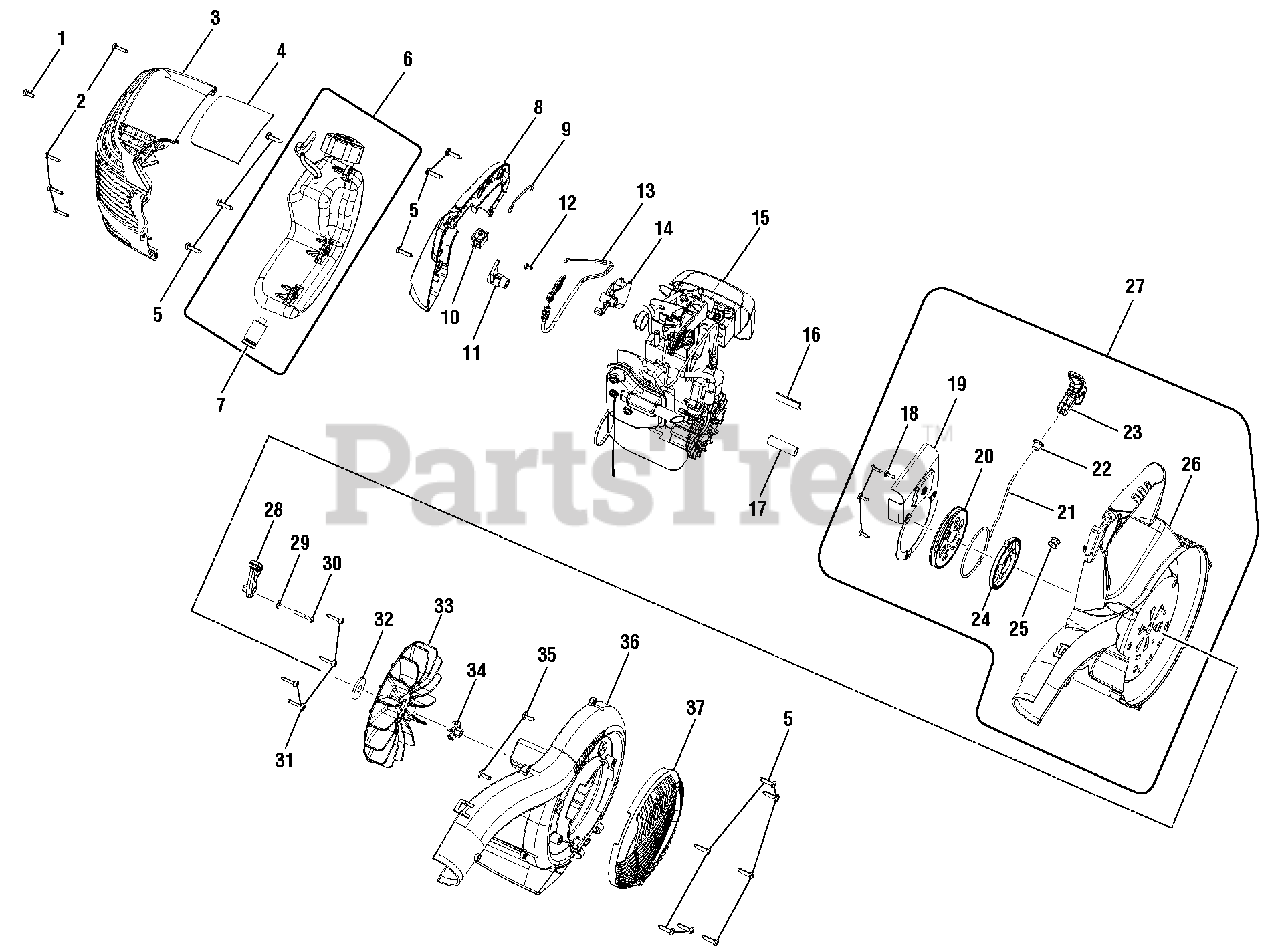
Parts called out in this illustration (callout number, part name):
1	Screw (M5 x 10.5 mm, T20 Torx Hd. )
2	Screw (M4 x 18 mm, T20 Torx Soc. Hd.)
3	Engine Housing
4	Heat Shield
5	Screw (#10-14 x 3/4 in, T25 Torx Pan Hd. T.F.)
6	Fuel Tank Assembly w/Cap
7	Fuel Filter
8	Handle Cover
9	Ground Wire
11	Trigger Lock
12	Screw (M3.5 x 7.5 mm, T20 Torx Pan Hd.)
13	Throttle Cable
15	Power Head Assembly
18	Screw (M4 x 12 mm, T20 Torx Truss Hd.)
20	Starter Pulley
21	Starter Rope
23	Starter Grip
24	Container Spring Assembly
26	Inner Volute
27	Lower Housing w/Starter
28	Cruise Lever
29	Washer (ID4.3 x OD12 x 1.5t)
30	Cruise Lever Screw (M8-14 x 25 mm, Special T20 Truss Hd.)
31	Screw (M4 x 23 mm, T20 Truss Hd. T.F.)
32	Washer (ID9.8 x OD34.27 x 2.28t)
33	Fan
34	Lock Nut (3/8 in.)
35	Screw (#10-14 x 1/2 in., T25 Torx Truss Hd.)
36	Outer Volute
37	Air Inlet Cover
